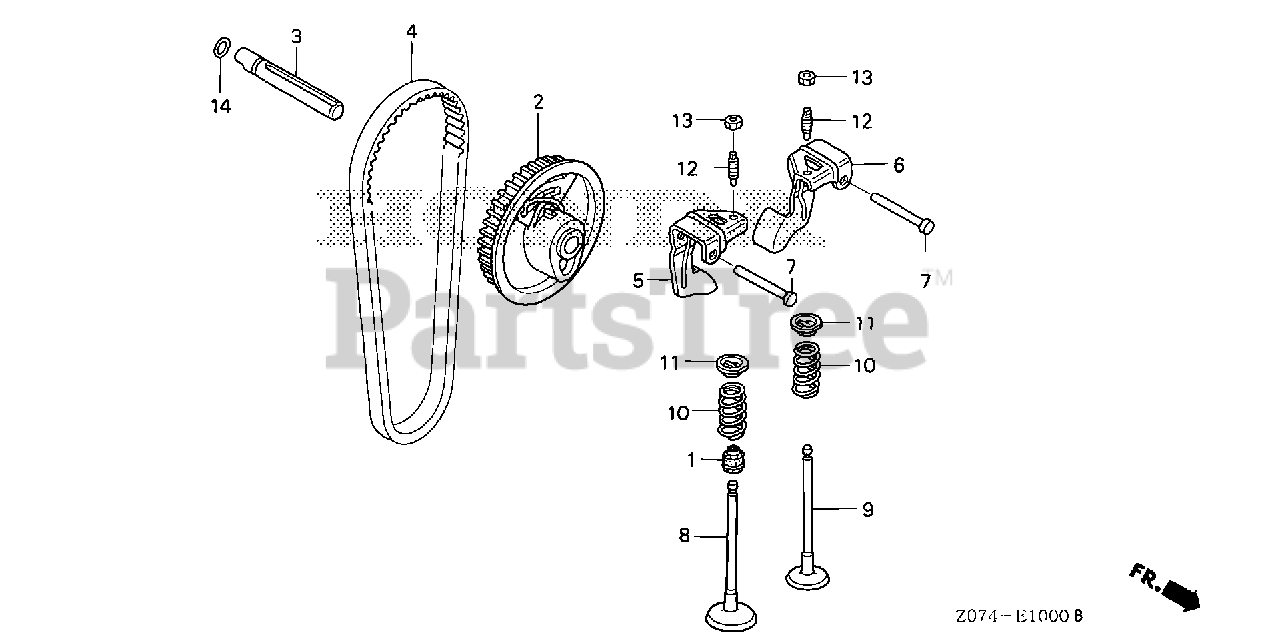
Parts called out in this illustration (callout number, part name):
1	SEAL, VALVE STEM
2	PULLEY, CAMSHAFT
3	SHAFT, CAM PULLEY
4	BELT, TIMING (61YU7 G-200)
5	ARM, IN. VALVE ROCKER
6	ARM, EX. VALVE ROCKER
7	SHAFT, ROCKER ARM
8	VALVE, IN.
9	VALVE, EX.
10	SPRING, VALVE
11	RETAINER, VALVE SPRING
12	SCREW, TAPPET ADJ.
13	NUT, TAPPET ADJ.
14	O-RING (6.8X1.9) (ARAI)
